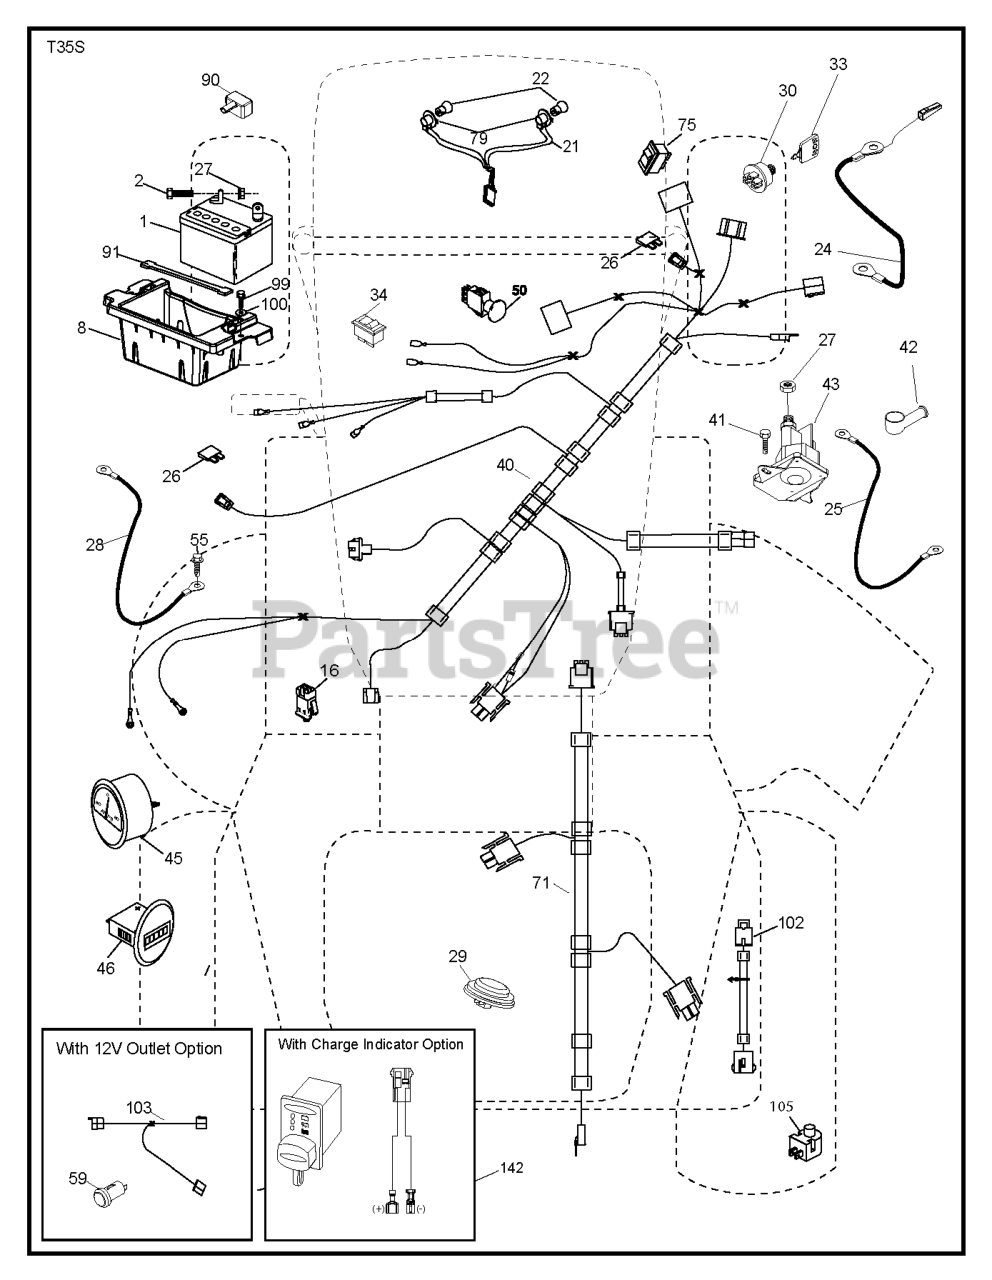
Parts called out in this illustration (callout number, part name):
1	Battery, Dry 30 Amp
2	BOLT.HEX.1/4.X.3/4.DICHROMATE
8	BOX.BATTERY.MOUNT.FRONT.LT
16	SWITCH INTERLOOK PUSH-IN
21	HARNESS.LIGHT W/4152J BULBS
24	CABLE.BATT.POS.WIRE.TG.DA SOL
25	CABLE.STARTER.6G.BL/RED.17.5
26	FUSE 20AMP
27	NUT
28	CABLE GROUND 6 GA 21" 90T BLK
29	SWITCH.SEAT.DELTA.OPC.
30	SWITCH.IGN.DELTA.W.LGH.ROS
33	KEY.CHAIN.BLISTER.PACK.GEN.USA
40	HARNESS.DASH.EDIFF.RND.CHR.EF
41	SCREW
42	TERMINAL COVER
43	SOLENOID.W/BRASS.PLUNGER
45	AMMETER GAUGE ROUND SNAP-IN
46	HOURMETER.GAUGE.RNK.SNAP.LS
50	RP.PTO.SWITCH.8 TERMINAL.BLACK
55	SCREW 5/16"
59	OUTLET.12-VOLT
71	HARNESS.IGN.CHASSIS.TEX.DCKLOC
75	SWITCH.ON/OFF.(DIFF.LOCK)
79	BULB HOLDER ASM.
90	COVER.TERMINAL.BATTERY
91	STRAP.BATTERY.MOUNT.FRONT(2 2)
99	SCREW HEXWSHR 1/4-20X3/4
100	WASHER
102	HARNESS PIGTAIL PCH TEX ROS
103	HARNESS.PIGTAIL.12V.OUTLET.
105	REVERSE SWITCH
142	RP HARNESS.JUMPER.CTEK
